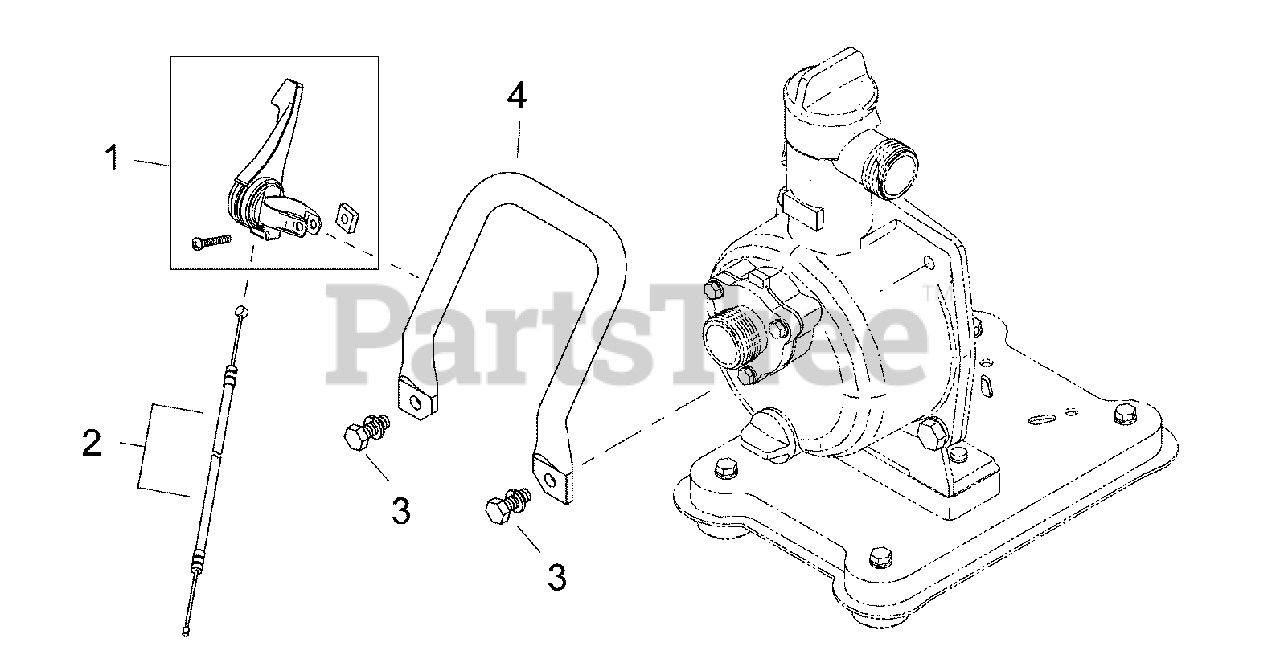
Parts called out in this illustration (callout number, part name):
1	THROTTLE LEVER ASSY
2	CABLE, THROTTLE
3	BOLT - 8X22
4	HANDLE
